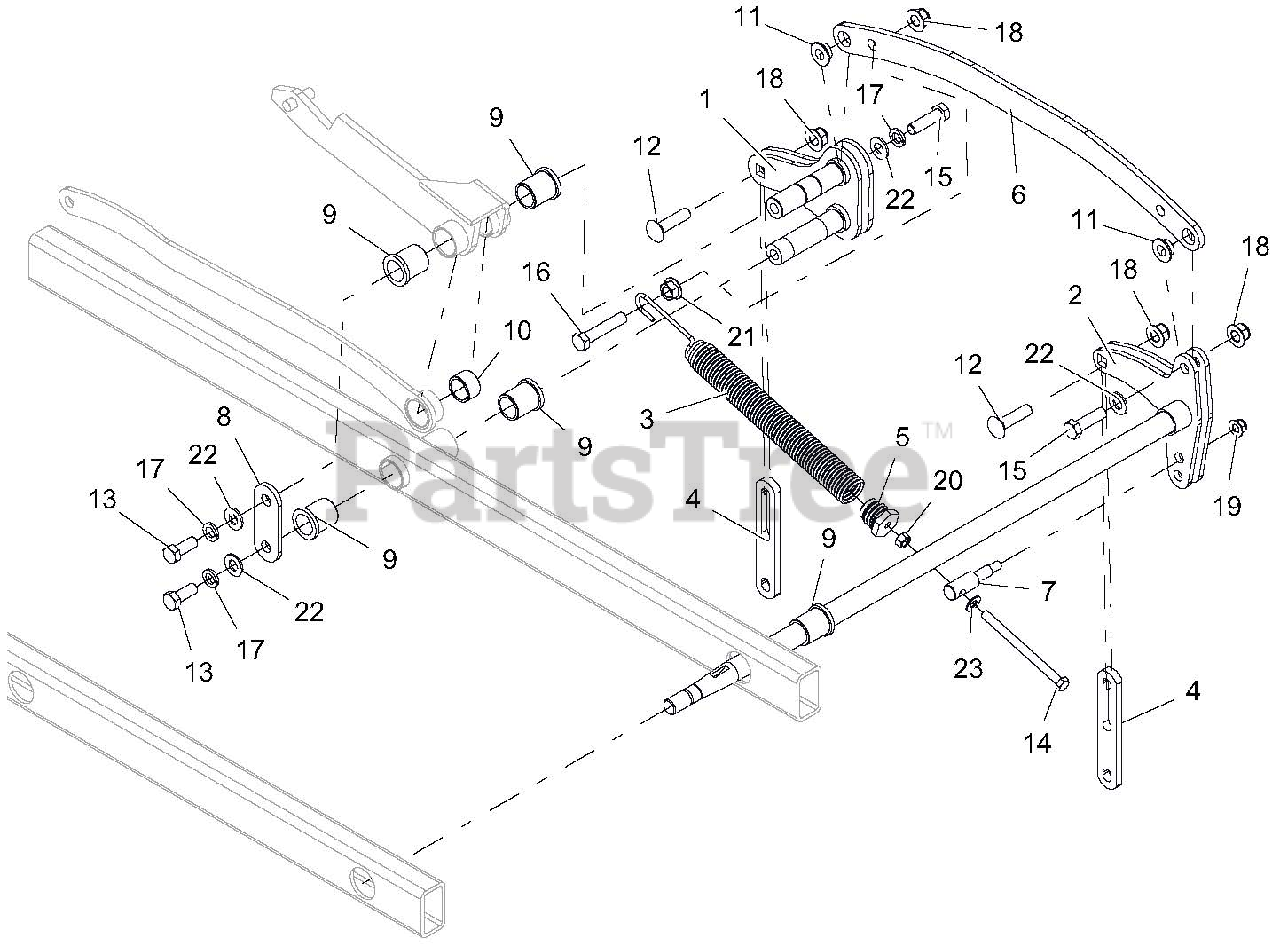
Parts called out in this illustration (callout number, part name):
1	WLDMT, DECK ARM
2	WLDMT, TAPERED SHAFT PROSTANCE
3	SPRG, DECK LIFT
4	LINK, DECK LIFT - LONG
5	PLUG, SPRG
6	ARM, DECK LIFT
7	TRUNION, DECK LIFT
8	PLATE, LIFT LINK ATTACH
9	BSHG-FLG 1.00X1.25X1.5X1.5
10	BSHG, 1.00 X 1.25 X .75
11	BSHG, FLANGE .515X.750X.420X1.12
12	BLT-RDHDSQNK .50-13X2.00 G5 Y
13	BLT-HEX .50-13X1.25 GR5 YWZC
14	BLT-HEX .38-16X5.00 GR5 YWZC
15	BLT-HEX .50-13X1.75 GR5 YWZC
16	BLT-HEX .50-13X2.50 GR5 YWZC
17	WSHR-LK .50X.125 REG YWZC
18	NUT-LK-NYL-FLG .50-13 YWZC
19	NUT-LK-NYL-FLG .38-16 YWZC
20	NUT-HEX .38-16 YWZC
21	NUT .50-13 WIZ FLANGE
22	WSHR-FL-STL.531X1.06X.095YWZC
23	WSHR-FL-STL.406X.812X.065 YWZ
